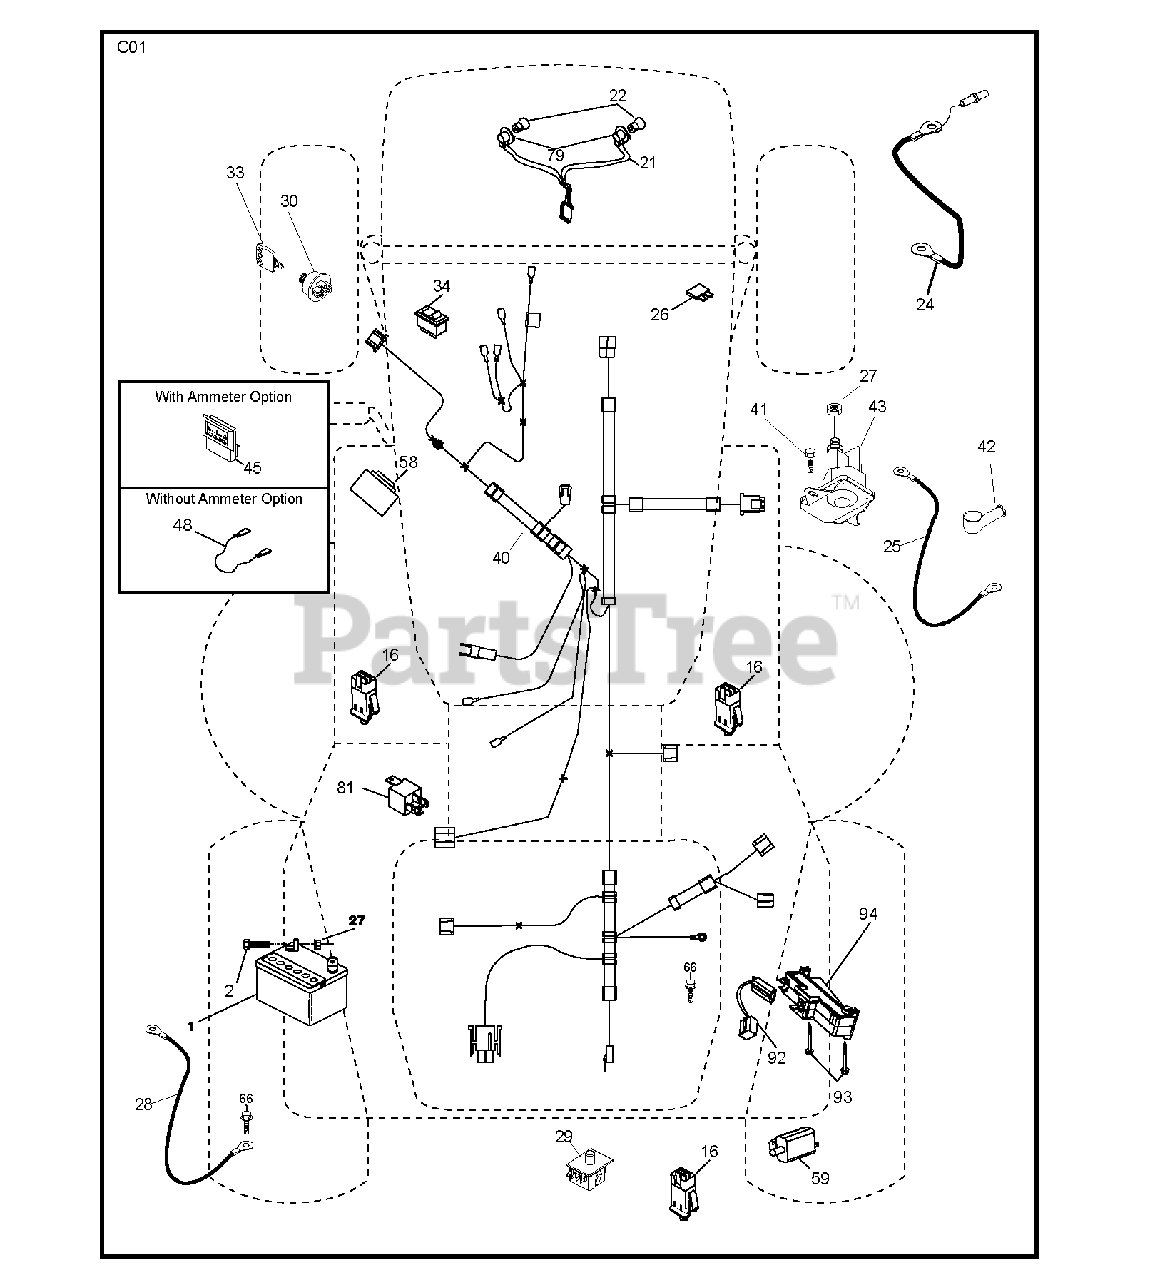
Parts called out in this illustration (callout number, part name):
1	REPL BY 532 12 38-99
16	SWITCH INTERLOOK PUSH-IN
21	HARNESS.W/LIGHT SOCKET
24	CABLE BATTERY
25	CABLE BATTERY 6 GA. 11" RED
27	NUT
29	SWITCH.SEAT.DP W/RAMPS
30	SWITCH.IGN.DELTA.W.LGH.ROS
33	KEY.CHAIN.BLISTER.PACK.GEN.INT
41	Hex Capscrew, 1/4-20
42	TERMINAL COVER
43	SOLENOID.W/BRASS.PLUNG
58	BUZZER
79	BULB HOLDER ASM.
92	HARNESS.PIGTAIL.CONSLE
93	SCREW.PLASTITE
94	MODULE.REVERSE.ROS
